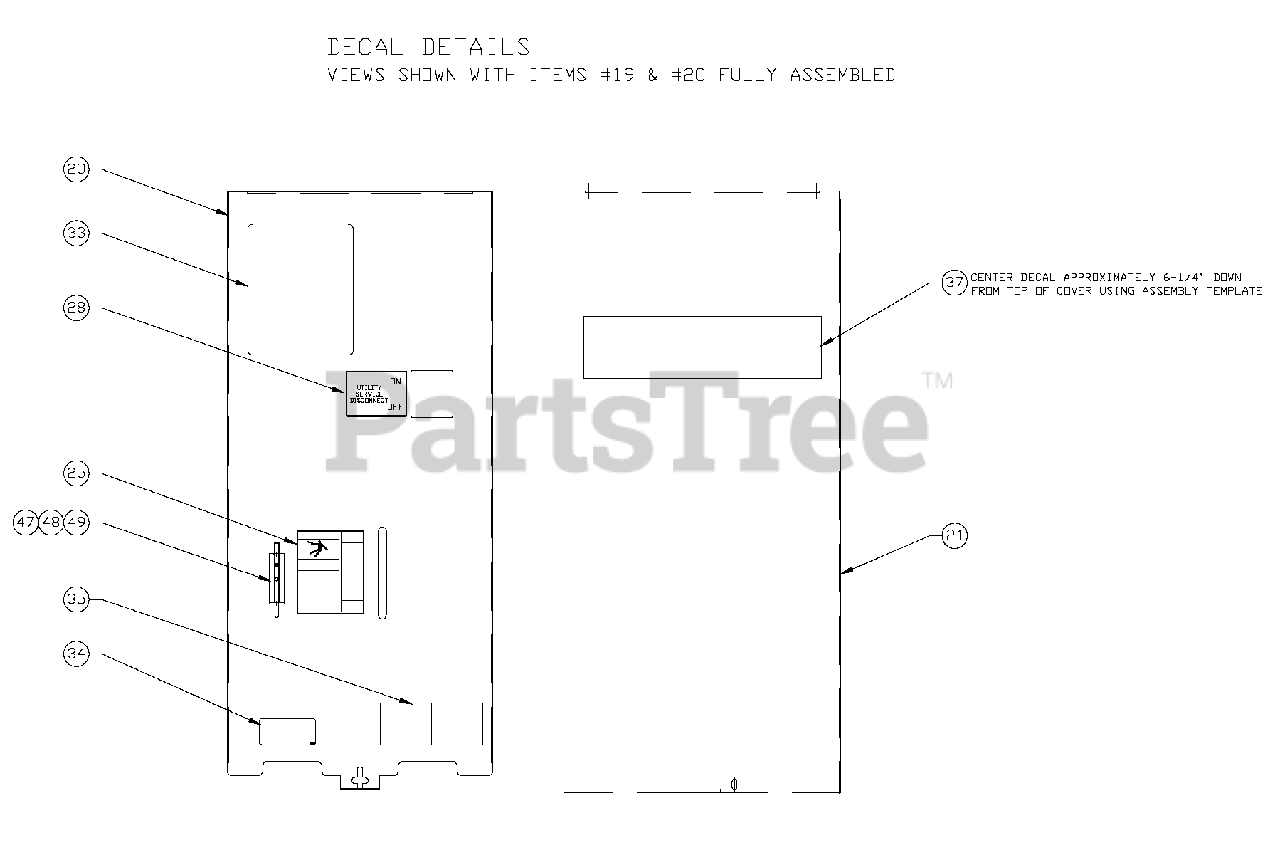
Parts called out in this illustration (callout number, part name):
20	COVER, INSIDE 200A DUAL BREAKER
21	COVER, TRANSFER SWITCH
25	DECAL, MANUAL OPERATING HANDLE
28	DECAL, UTILITY DISCONNECT
33	DECAL, TEST SEQUENCE
34	DECAL, LIVE CIRCUIT ENG/FRN/SPN
35	DECAL, TERMINAL SHOCK HZD BI
37	DECAL, SIEMENS 3.2" X 11.8"
47	BRACKET, ARM EXTENDER
48	RIVET POP .156 X .362 AL
49	ARM EXTENDER PIN
